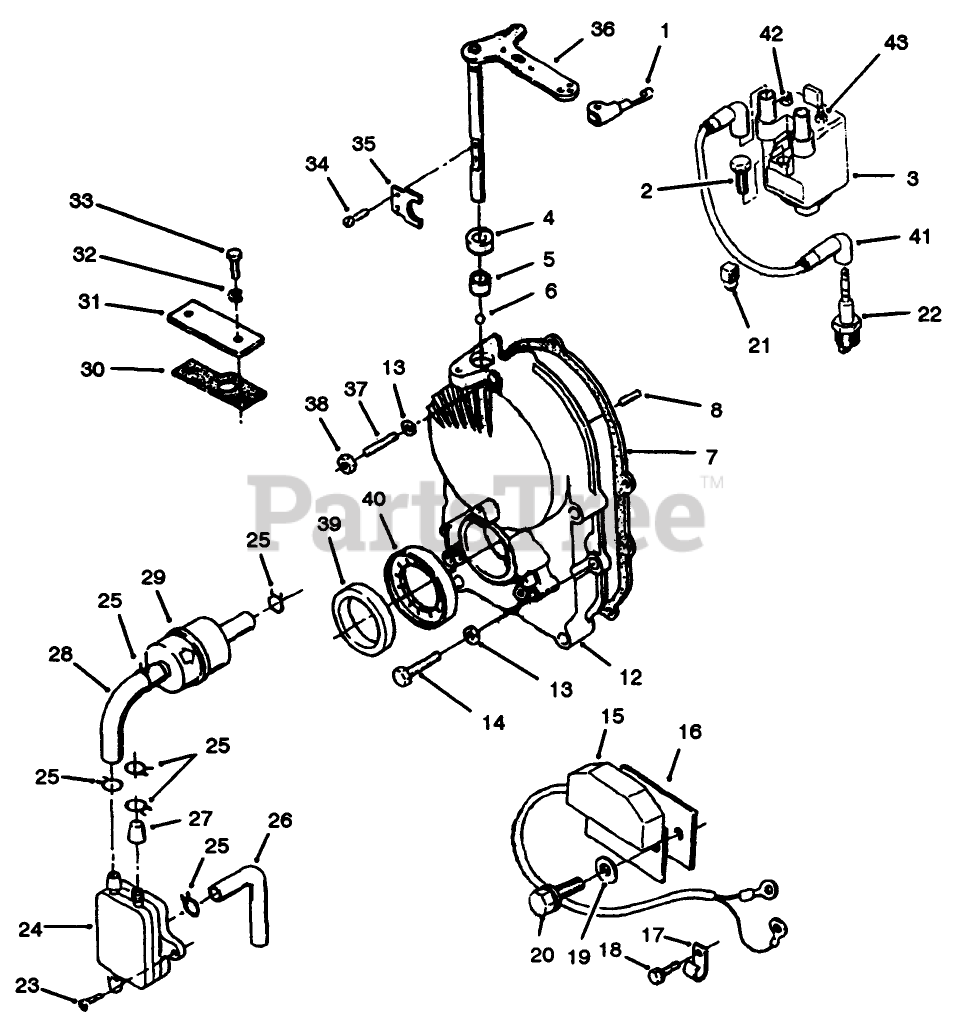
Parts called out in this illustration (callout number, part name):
2	SCREW-HH
3	COIL-BATTERY IGNITION
5	BEARING
7	GEAR CASE MTG GASKET
8	PIN-DOWEL
12	Kit-Gearcase (Incl. Ref. #4-6, 8-11, 26, & 34-36)
13	WASHER
14	SCREW-HH
15	CONTROL-IGNITION
16	INSULATOR-IGN MODULE
17	CLIP-WIRE
18	SCREW-HH
19	WASHER-LOCK, INT
20	SCREW-HH
21	WIRE ROUTING CLIP
22	SPARK PLUG
23	SCREW-TAPPING PAN HD
24	PUMP-FUEL
25	CLAMP
26	HOSE-VACUUM
27	CAP-FUEL OUTLET
28	Hose
29	FILTER-FUEL
30	GASKET
31	PLATE-COVER
32	WASHER-FLAT
33	SCREW-HH
34	Screw
36	SHAFT/ARM-GOVERNOR
37	STUD-GEAR COVER
38	NUT-HEX
40	ROTOR-IGNITION
41	Cable Plug 9" Long
42	NUT-HEX FLANGE
43	NUT-HEX FLANGE
